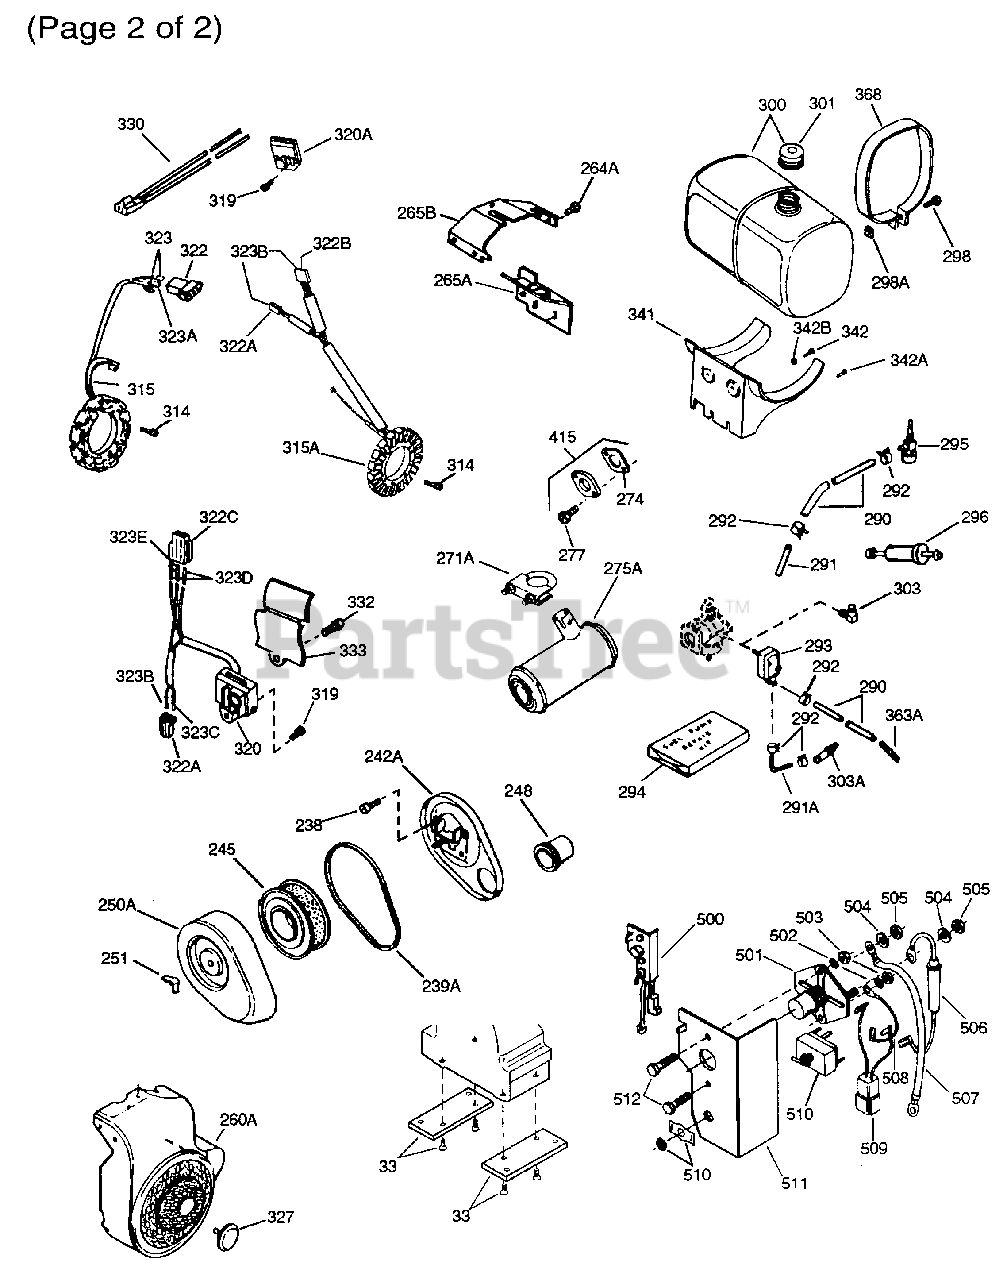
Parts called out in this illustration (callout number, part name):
16B	Governor Spring Plate
238	Screw, 10-32 x 5/8"
239A	Air Cleaner Gasket
242A	Air Cleaner Bracket
245	Air Filter
248	Air Cleaner Tube
251	Wing Nut, 1/4-20
261A	Screw, 1/4-20 x 7/16"
264A	Screw, 10-24 x 1/2"
265A	Cylinder Head Cover
265B	Cylinder Head Cover (upper)
274	* Exhaust Gasket
290	Fuel Line (8.62")
292	Fuel Line Clamp
293	Pulse Pump (Incl. 294)
294	Pulse Pump Repair Kit
303A	Fuel Fitting
314	Screw, 10-32 x 1-1/8"
315	Alternator Coil (20 Amp) Incl. 322,32 3&323A
319	Screw, T-30, 1/4-20 x 1/2"
320	Regulator Incl. 322A,322C,323B,323C, 232D&323E
322	Connector Body
322A	Connector Body
322C	Connector Body
323	Terminal
323A	Terminal
323B	Terminal
323C	Terminal
323D	Terminal
323E	Terminal
355	Starter Handle
363A	Fuel Line Spring
